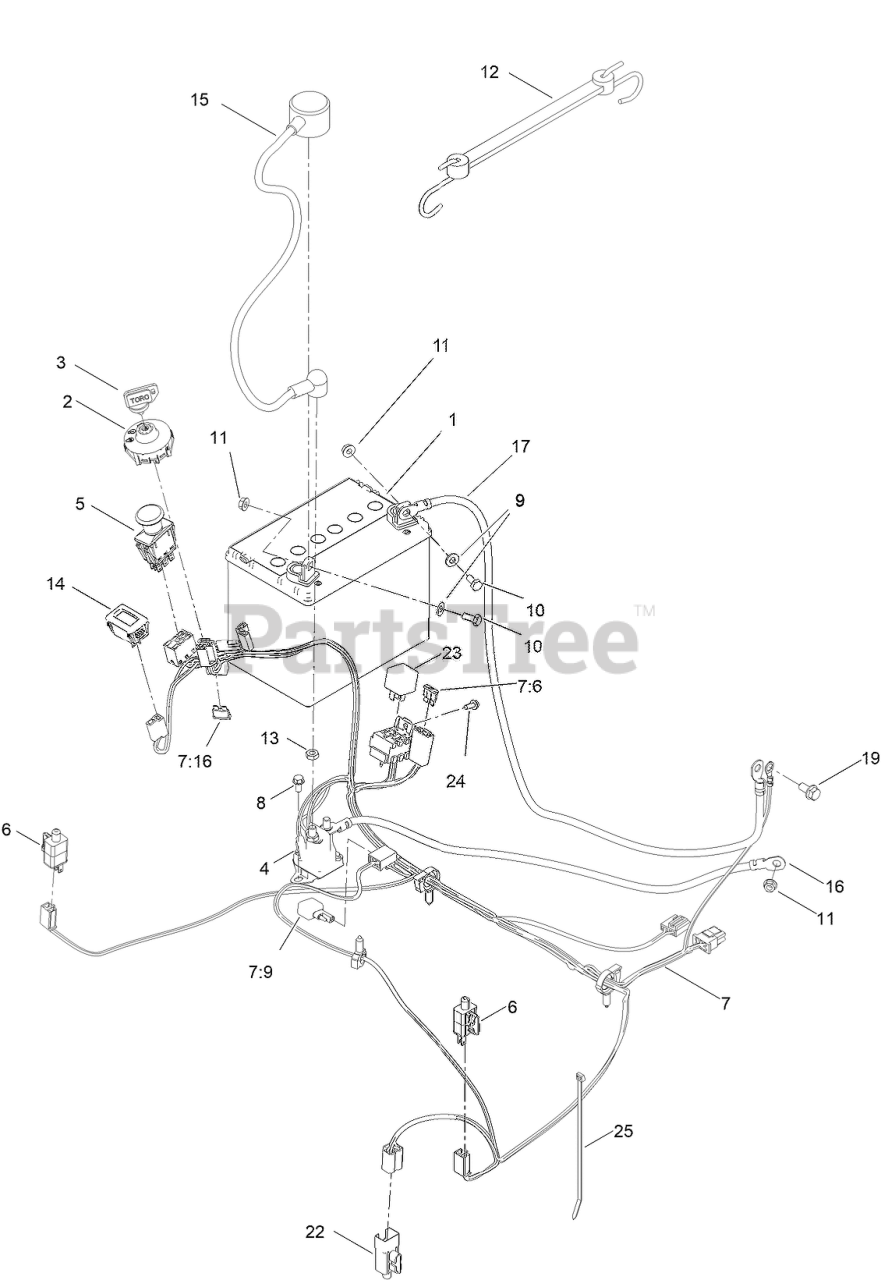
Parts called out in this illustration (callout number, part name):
1	BATTERY-DRY
2	SWITCH-IGNITION
3	KEY-IGNITION
4	SOLENOID
5	SWITCH-PTO
6	SWITCH
7	HARNESS-WIRE
7:6	FUSE-BLADE, 25 AMP
7:16	FUSE-BLADE, 15 AMP
8	SCREW-HWH
9	WASHER-FLAT
10	SCREW-HH
11	NUT-HF
12	HOLDDOWN-BATTERY
13	NUT-HJ
14	HOURMETER
15	CABLE-BATTERY, POSITIVE
16	CABLE-BATTERY, RD ASM
17	CABLE-BATTERY, NEGATIVE
19	SCREW-HHF
22	SWITCH-REVERSE
23	RELAY
24	SCREW-TAPTITE
25	TIE-CABLE
